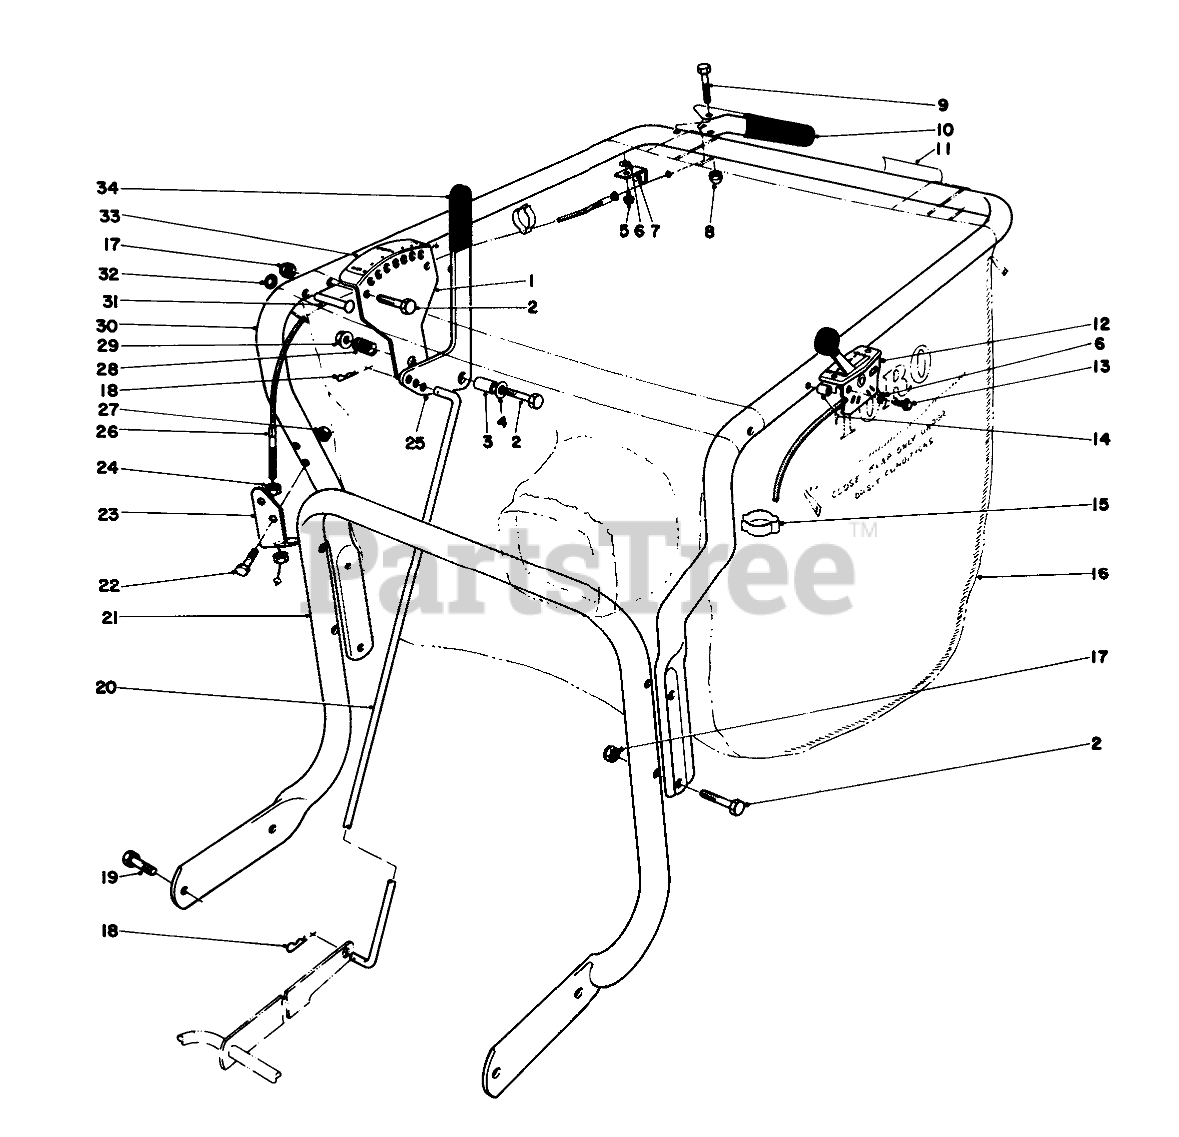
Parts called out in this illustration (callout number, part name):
1	Adjustment Bracket
2	SCREW-HH
3	SPACER
4	SCREW-HH
5	SCREW
6	WASHER-LOCK, EXT
7	RETAINING-CLIP
8	NUT-CAP
9	SCREW-HH
10	LEVER W/GRIP
11	TRACTION CONT DECAL
12	THROTTLE CONTROL
13	10-24 X 1 PAN HD SCR
14	SPACER
16	Bag-Vacuum
17	NUT-LOCK, CONE
18	PIN-COTTER
19	SCREW-HH
20	HEIGHT ADJ. ROD
21	HANDLE
22	SCREW-HH
23	MOUNT-BOWDEN, LOWER
24	NUT-KEPS
25	Handle-Adjustment
26	FWD ASSY CABLE
27	NUT-LOCK, CONE
28	SPRING-COMPRESSION
29	NUT-HF
30	HANDLE-UPPER, VACUUM
31	RIVET
32	NUT-PUSH IN
33	HT ADJ DECAL
34	GRIP-HANDLE
